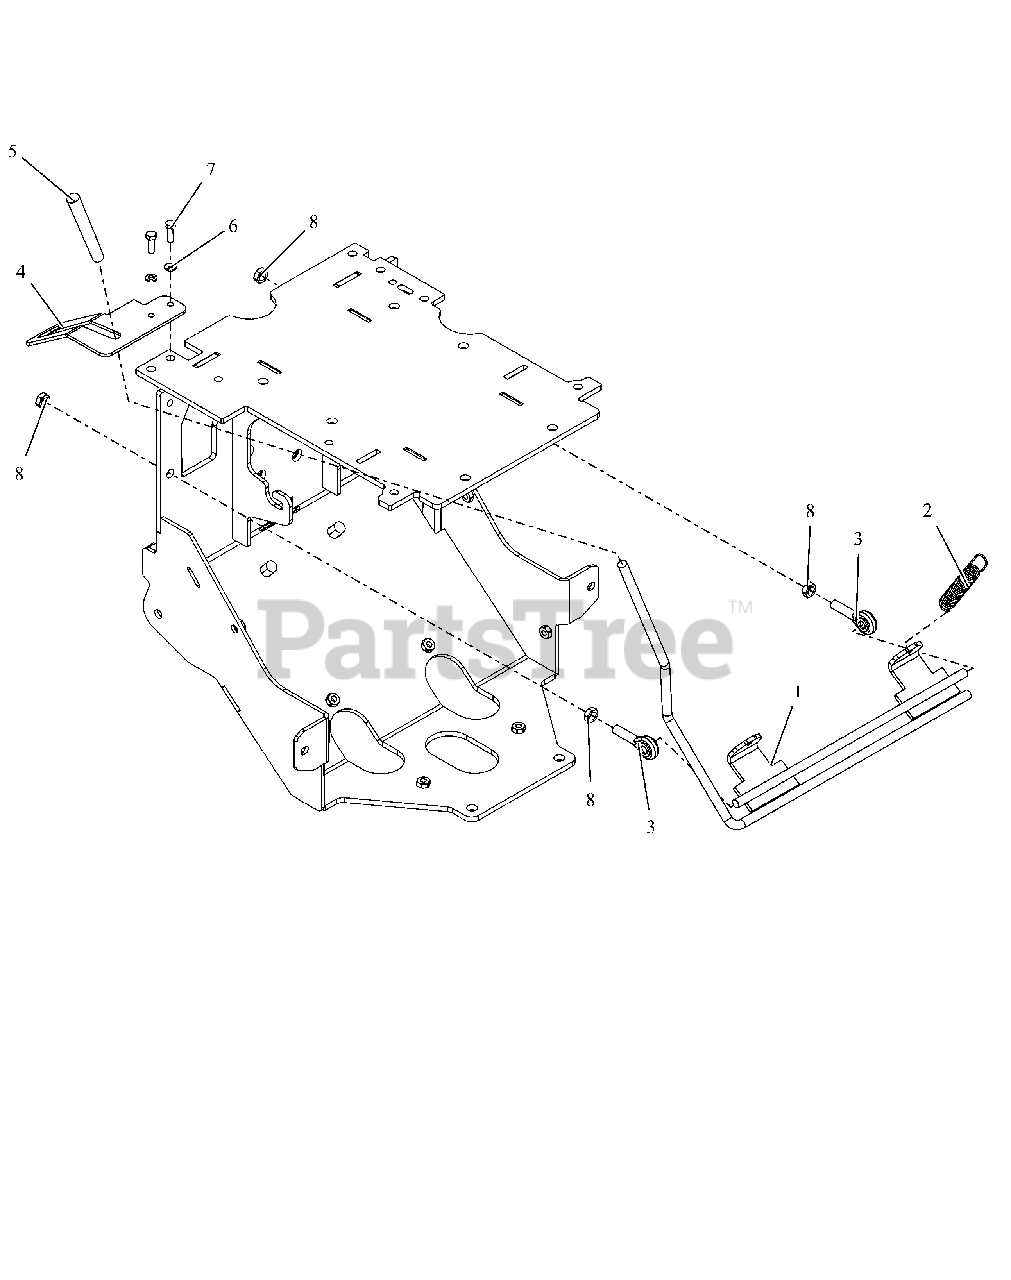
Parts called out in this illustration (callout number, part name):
1	WLDMT, STEERING LOCK
2	SPRG, EXT .653 X .063 X 2.755
3	ROD, END 3/8 RH
4	PLATE, STEERING LOCK PROFILE
5	GRIP, PLASTIC
6	WSHR,LK-REG .250X.062 ZCC
7	BLT, HEX M6-1.0 X 20 G8.8 ZCC
8	NUT, HEX-JAM .38-24 ZCC
